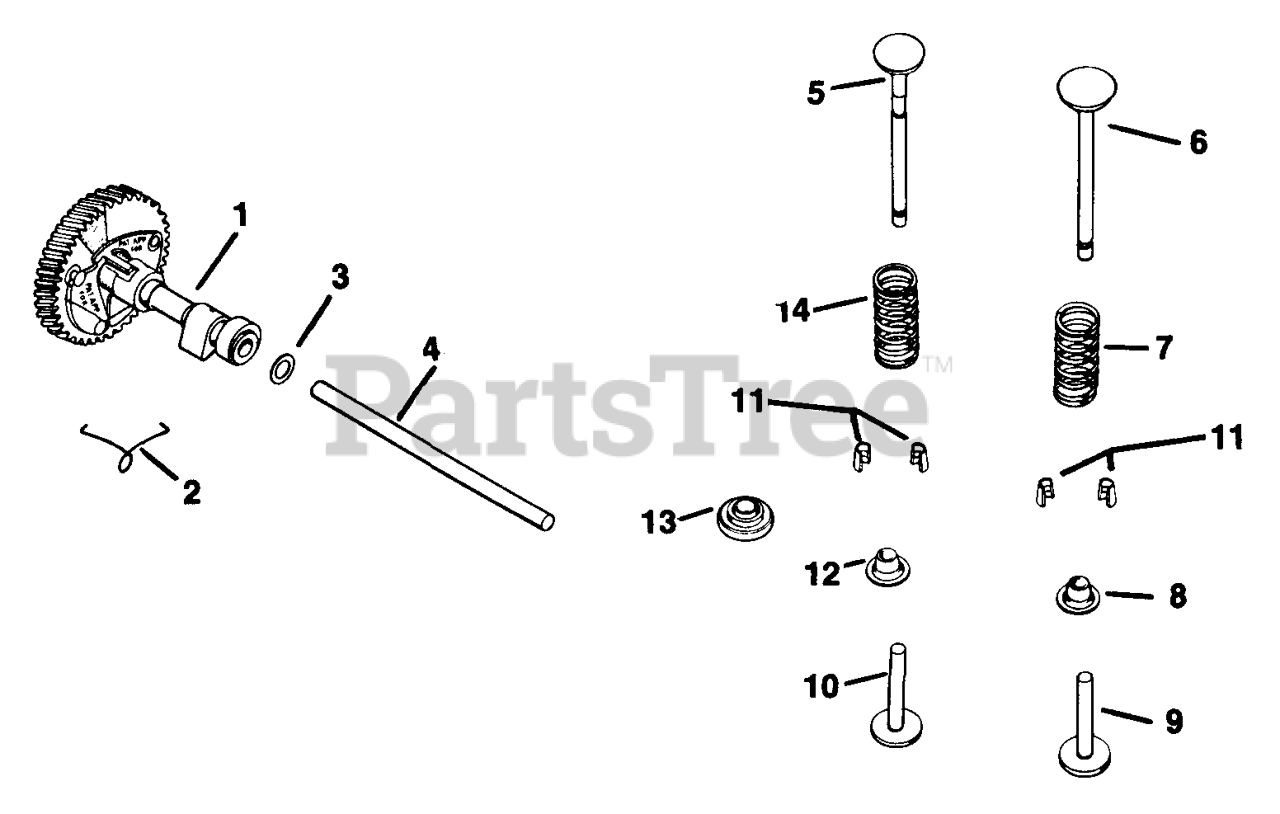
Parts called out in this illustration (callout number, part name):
1	KIT, CAMSHAFT
2	SPRING, ACTUATING-DISCONTINUED
4	PIN - USE 41 380 03
5	VALVE - DISCONTINUED
6	VALVE - DISCONTINUED
7	SPRING - DISCONTINUED
8	RETAINER, VALVE SPRING
9	TAPPET - DISCONTINUED
11	KIT, RETAINER
13	ROTATOR - USE 52 413 01
14	SPRING - DISCONTINUED
